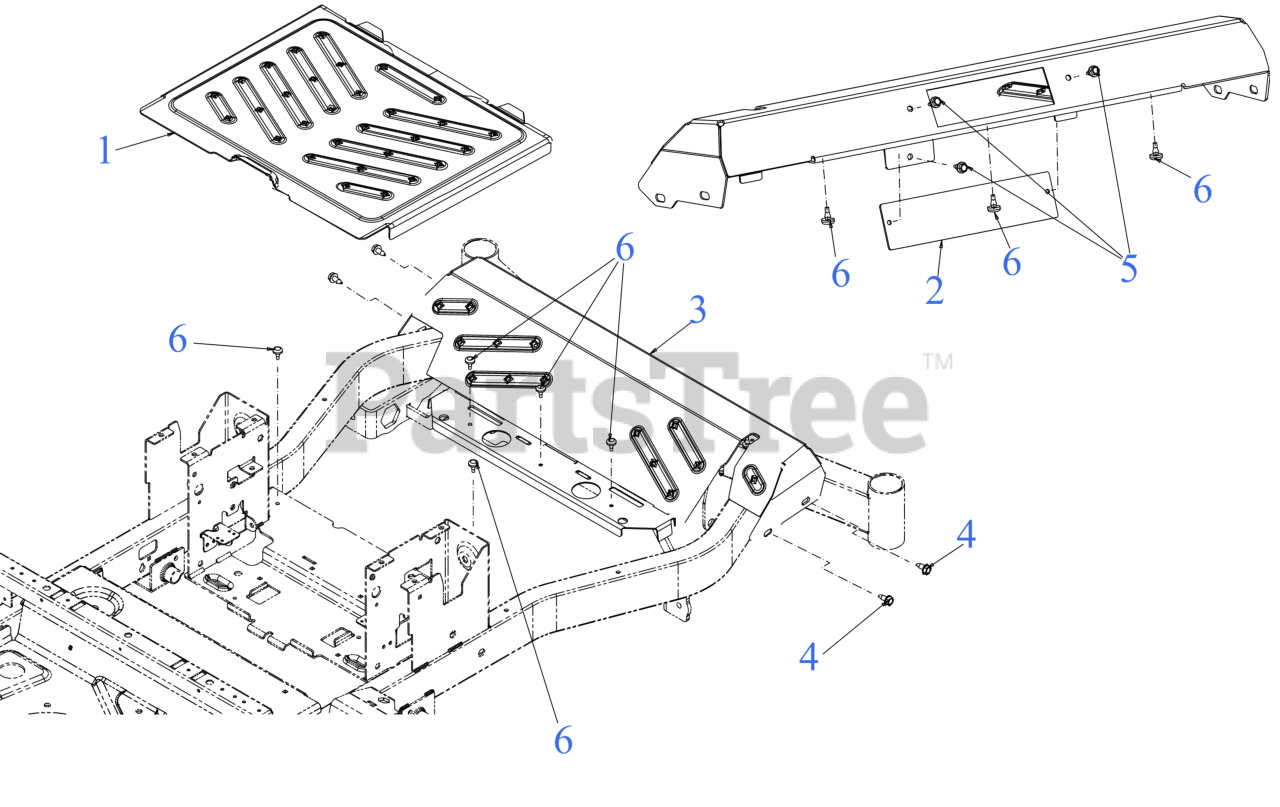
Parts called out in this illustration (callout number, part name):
1	FLOORBOARD
2	FOOTREST PLATE
3	FOOTREST BRACKET
4	SCREW 5/16-18 x .750
5	SCREW 1/4-20X.625
6	RUBBER BUMPER
